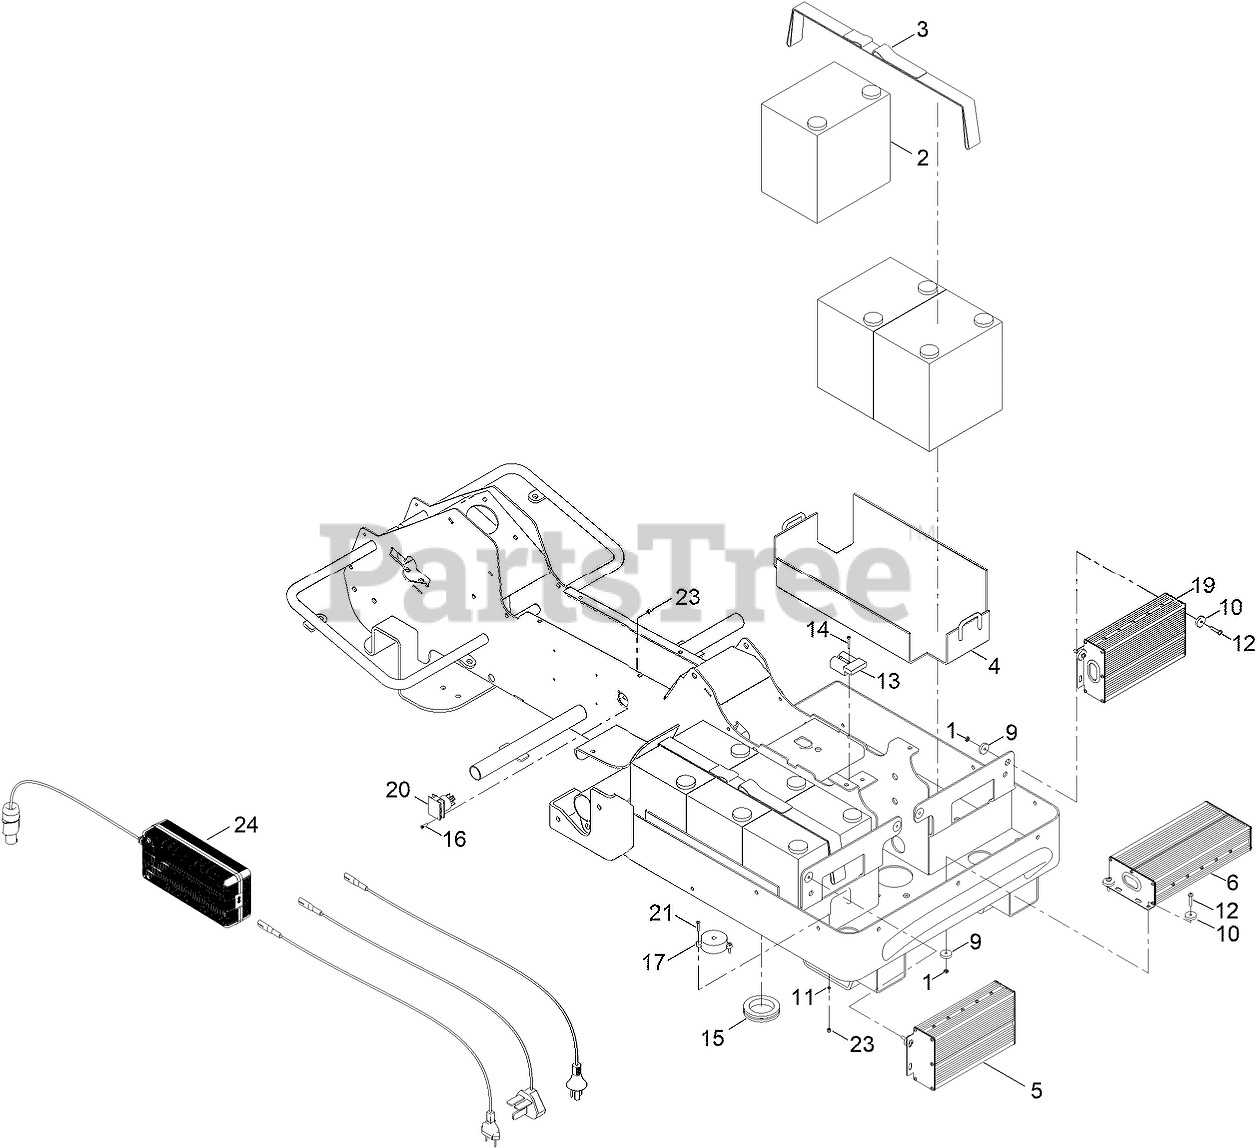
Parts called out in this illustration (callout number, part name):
2	BATTERY
3	STAP, BATTERY
4	HOLDER, BATTERY
5	CUTTING CONTROLLER
6	DRIVING CONTROLLER
9	FLAT BUSH, RUBBER
10	BUSH, RUBBER
11	SPRING WASHER
13	CONNECTOR, ELECTRICAL
15	INSERT, RUBBER CABLE LARGE
19	CUTTING CONTROLLER
20	POWER CONNECTOR ASM
23	NUT-NYLOC
24	CHARGER
